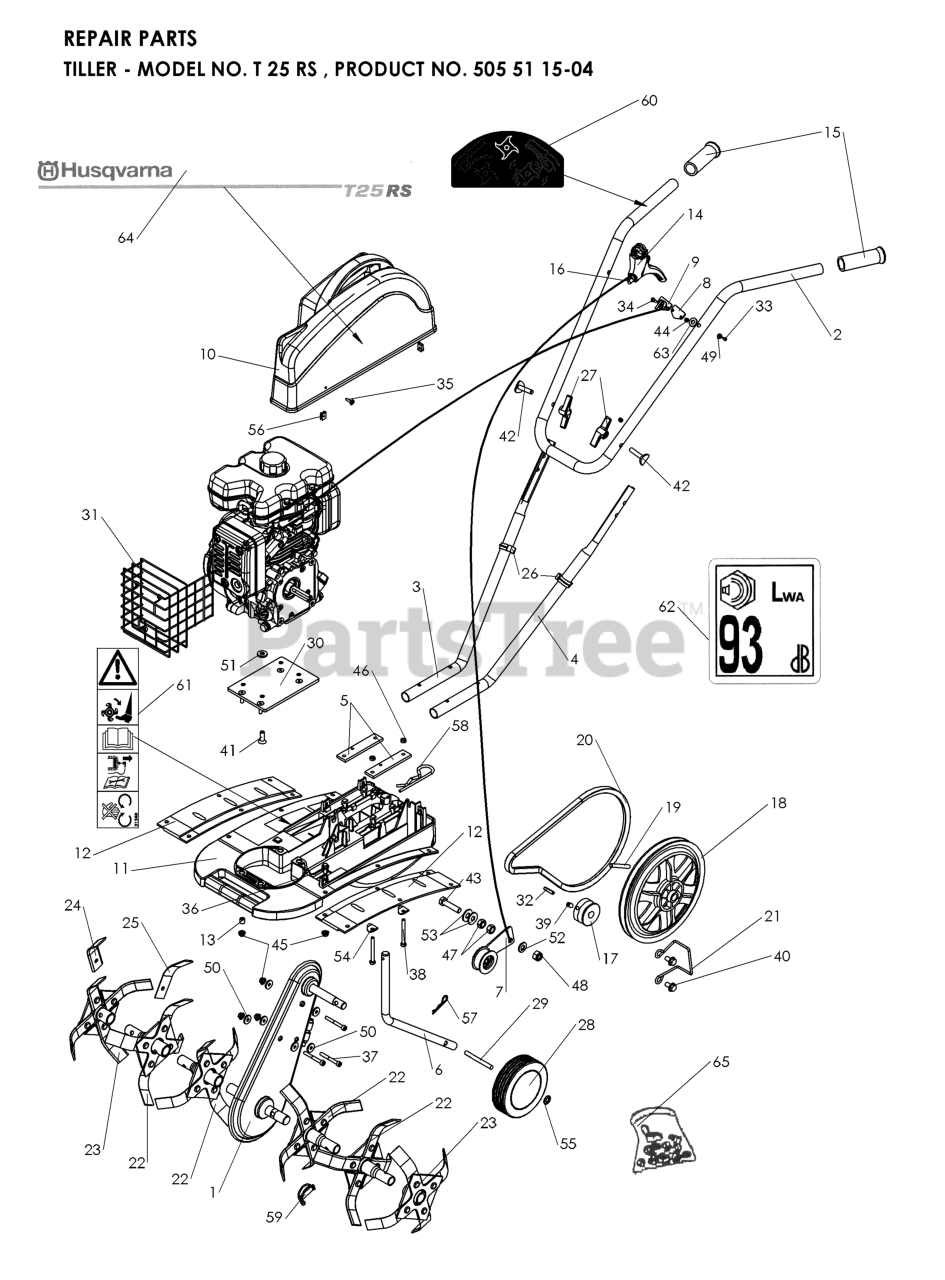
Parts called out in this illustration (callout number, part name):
8	SUPPORT SWITCH
16	CABLE CLUTCH
33	SCREW 0300080301
46	Blocking nut M 6 Z
52	WASHER
57	COTTER PIN
